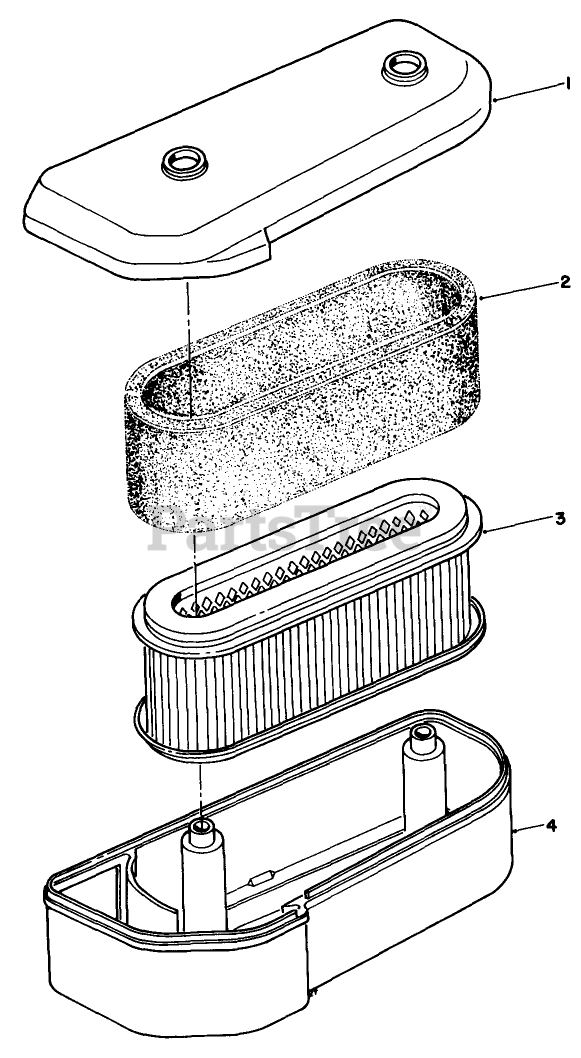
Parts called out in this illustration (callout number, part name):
1	Cap-Air Cleaner
2	Element
3	Element
4	CASE-Air Filter
